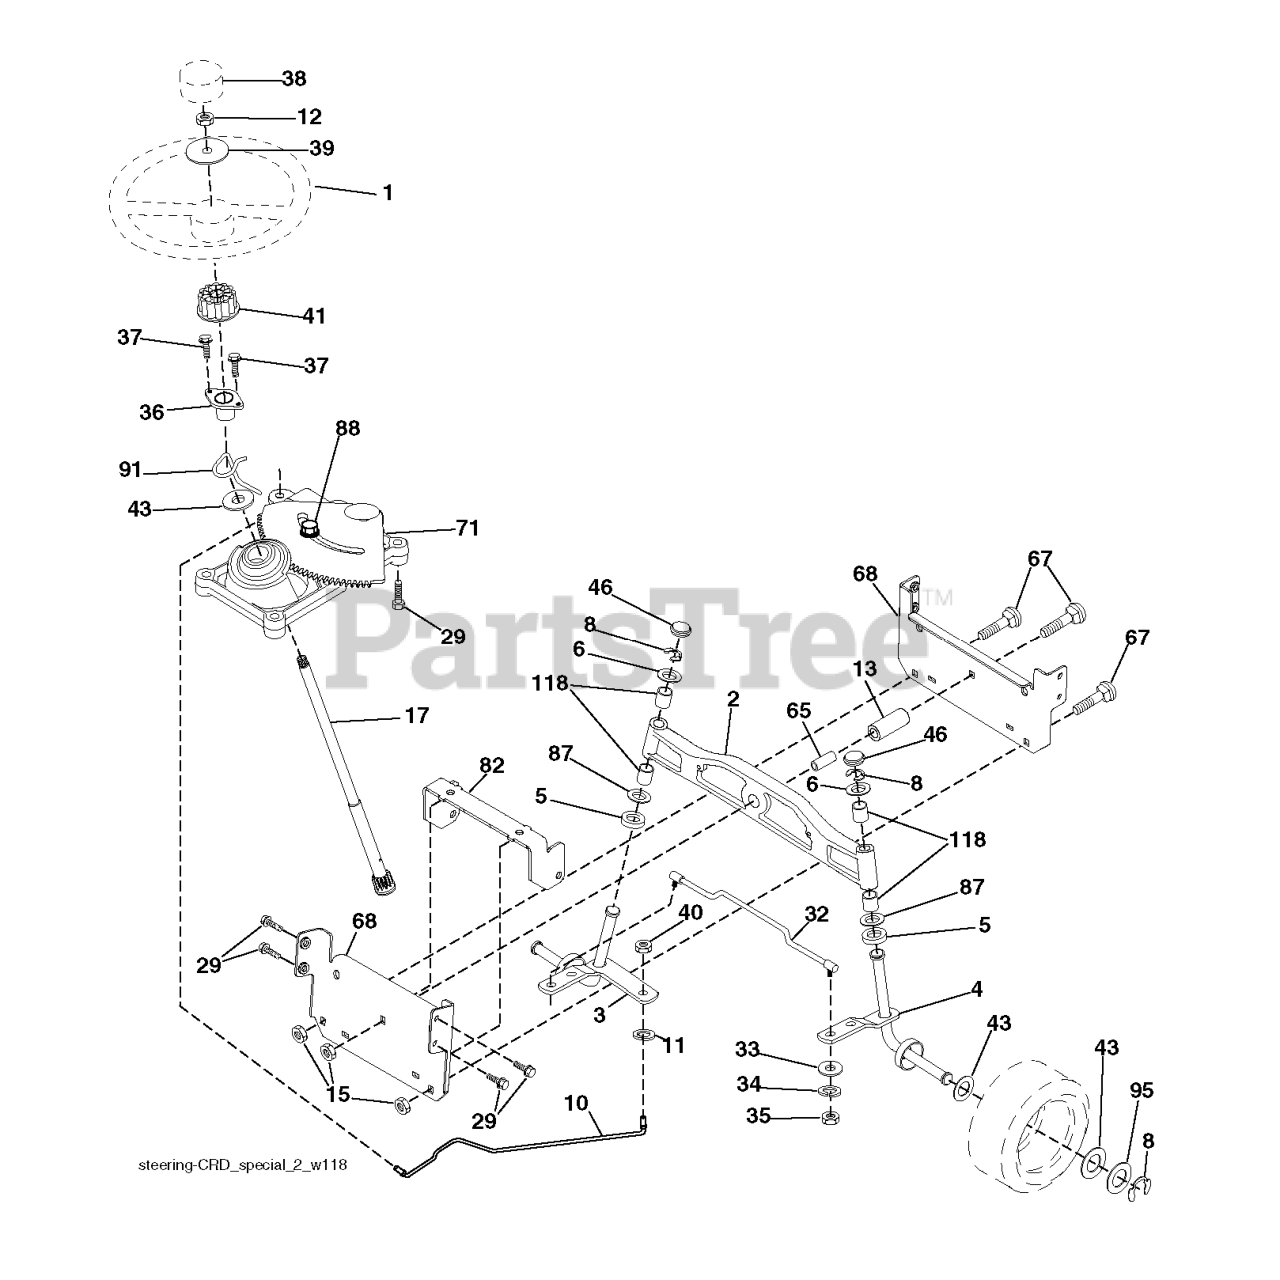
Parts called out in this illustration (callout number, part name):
1	RP WHEEL.STEER.HUSQ.PREM.OVMLD
2	AXLE.ASM.LT.CAST.LGHTWGHT
3	SPINDLE.ASM.LH.15"TIRES
4	SPINDLE.ASM.RH.15"TIRES
5	THRUST WASHER
10	DRAGLINK.15".TIRES.2001
11	WASHER, LOCK 3/8
12	NUT.HEX.1/2-20
13	TUBE, PIVOT AXLE
15	NUT LOCK FLG 3/8-16 UNC
17	SHAFT ASM STRG
29	SCREW, 3/8-16X3/4
33	WASHER M
34	WASHER.LOCK.HVY.HLCL.SPR.5/16
35	NUT, CROWNLOCK
36	BUSHING, STRG. BLK
37	SCREW.TT.#10-32X.5.3/8.FLANGE
38	RP INSERT.CAP.WHL.STRG.HUSQ.
39	WASHER 9/16"ID, 2 3/8"OD
40	NUT CROWNLOCK 3/8-24
41	ADAPTER, WHEEL STNG..
46	CAP.SPINDLE.BLACK
65	SPACER.BRACE.AXLE
67	BOLT CARRIAGE
68	BRACE.AXLE.15"TIRES
71	STEERING ASM
82	BRACKET.SUSP.CHASSIS.FRONT.15
87	WASHER, FLAT .781 X 1 1/2"
88	BOLT, SHOULDER 7/16-20
91	CLIP.STEERING
95	WASHER.HARDENED
118	BUSHING, AXLE CAST
